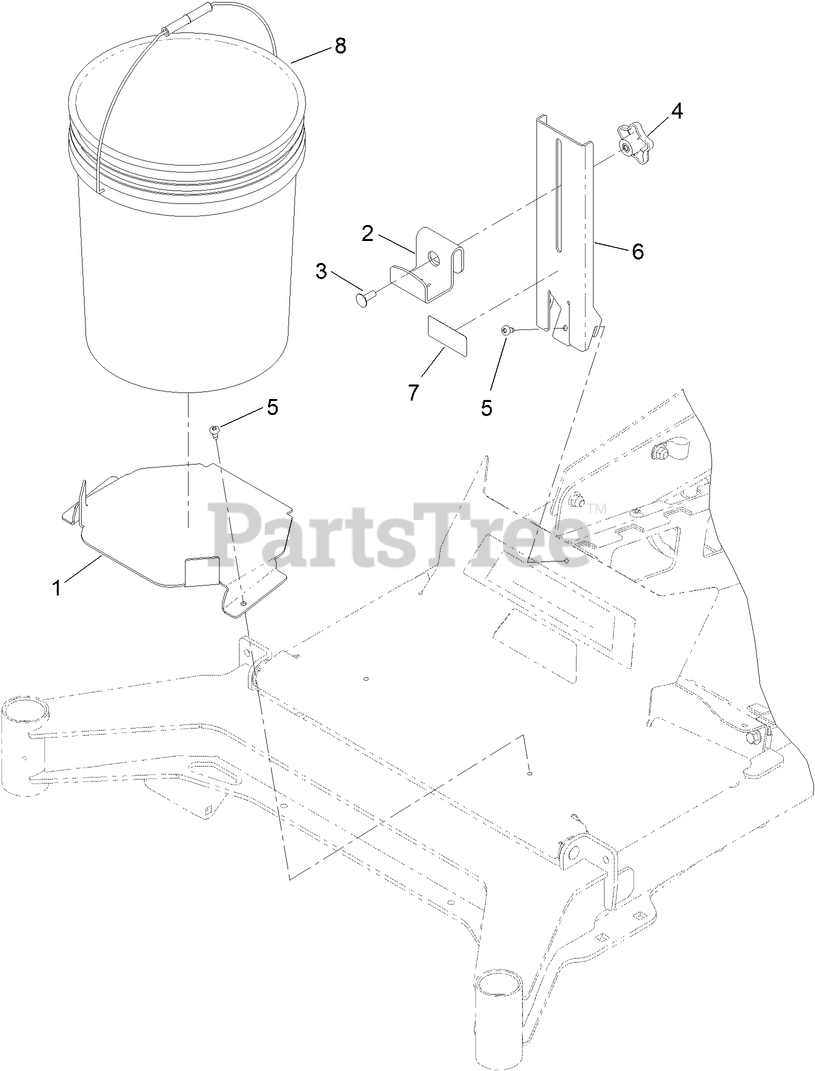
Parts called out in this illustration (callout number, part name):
1	PLATE, BUCKET-MOUNT
2	BRACKET-TOP
3	BOLT-CARR
4	KNOB-HANDLE
6	BRACKET, MOUNT
7	DECAL-WEIGHT, MAXIMUM
8	BUCKET-5 GALLON
